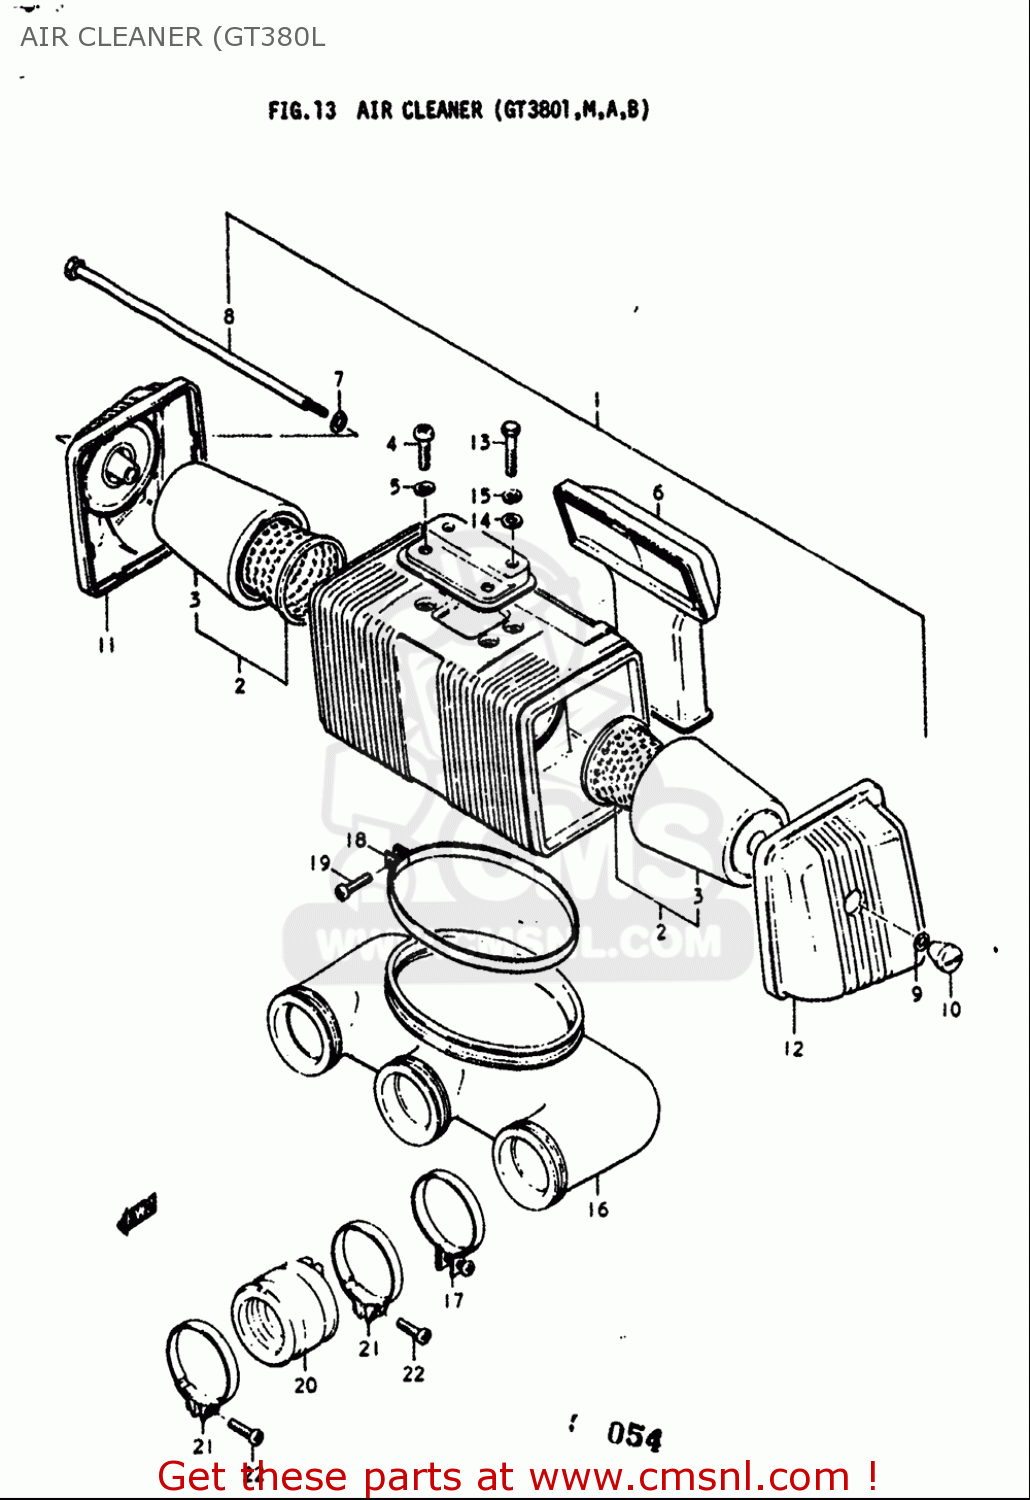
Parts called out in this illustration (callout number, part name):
2	FILTER ASSY,AIR CLEANER
3	FILTER ASSY,AIR CLEANER
4	SCREW
5	WASHER,LOCK
9	WASHER
10	NUT,AIR CLEANER PLUG
13	BOLT(6X35)
14	WASHER(6.5X20X1.2)
15	WASHER,LOCK
17	CLAMP
19	SCREW
20	PIPE,INTAKE
21	CLAMP
22	SCREW
